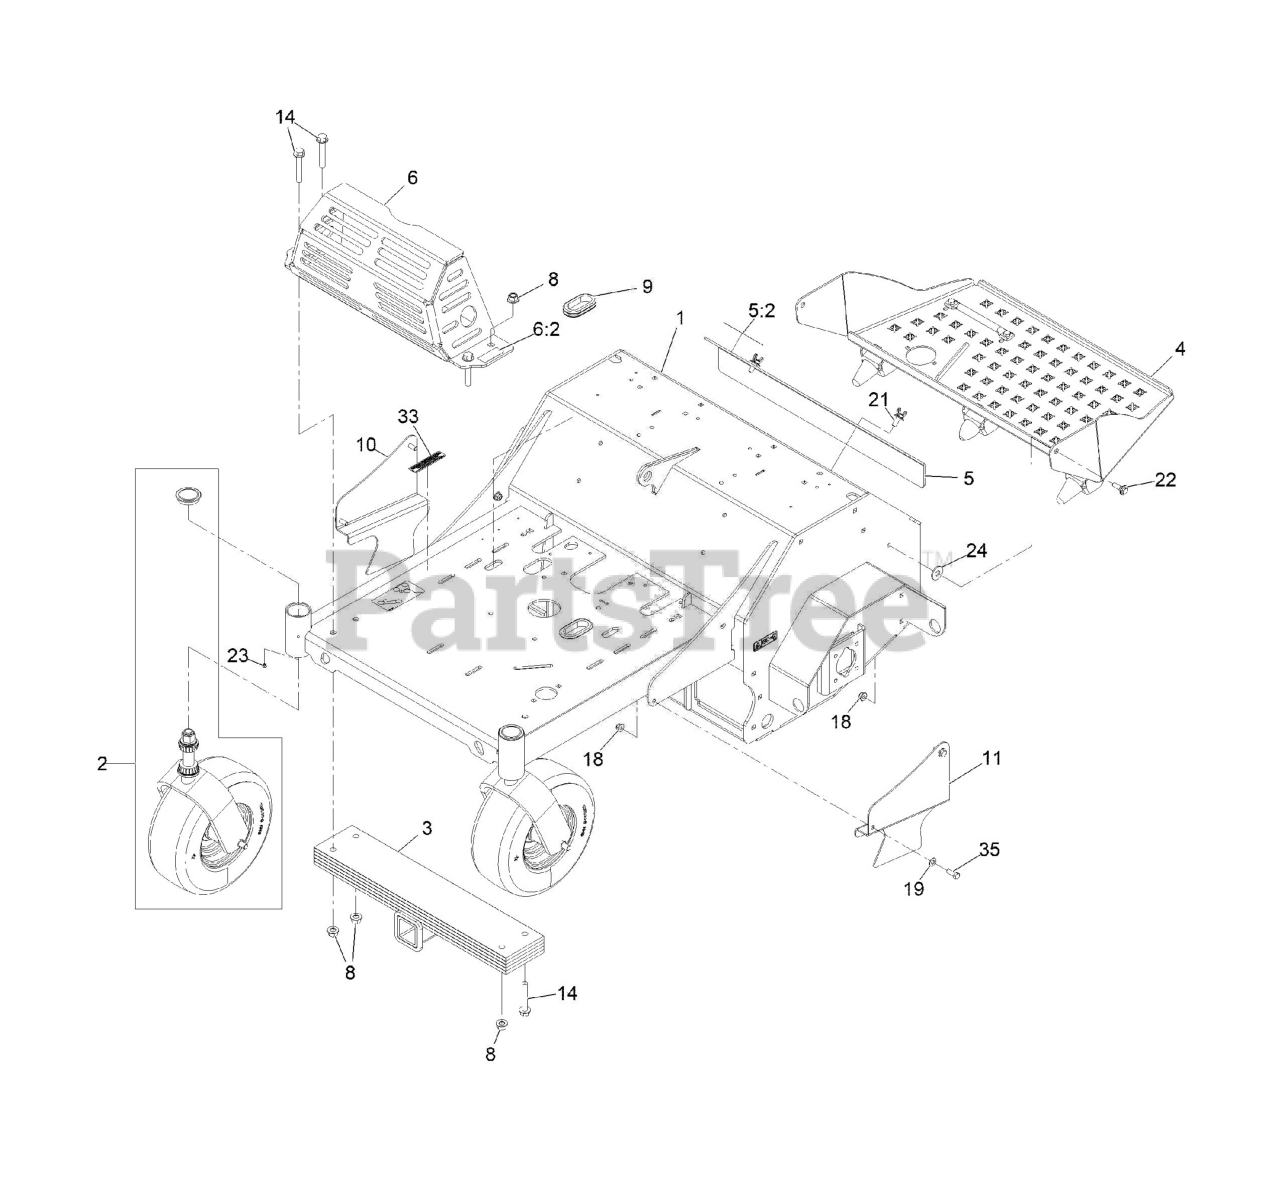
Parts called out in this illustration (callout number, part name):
1	Main Frame ASM
2	Front Caster ASM W/Fork
3	ASM-WEIGHT
4	PLATFORM W/ROCKER ASM
5	ACCESS COVER ASM
5:2	DECAL-OPERATION, TINE GRO
6	MUFFLER GUARD ASM
6:2	DECAL-SURFACE, HOT
8	Nut-Lock 1/2-13
9	GROMMET
10	GUARD-CHAIN, RH
11	GUARD-CHAIN, LH
14	SCREW-HF
18	NUT-HF, NI
19	WASHER-FLAT
21	Screw-Sems (3/8-16 X 1)
22	SCREW-SHOULDER, HWH
24	WASHER-FLAT
33	DECAL-ARRESTOR, SPARK
35	SCREW-HH
